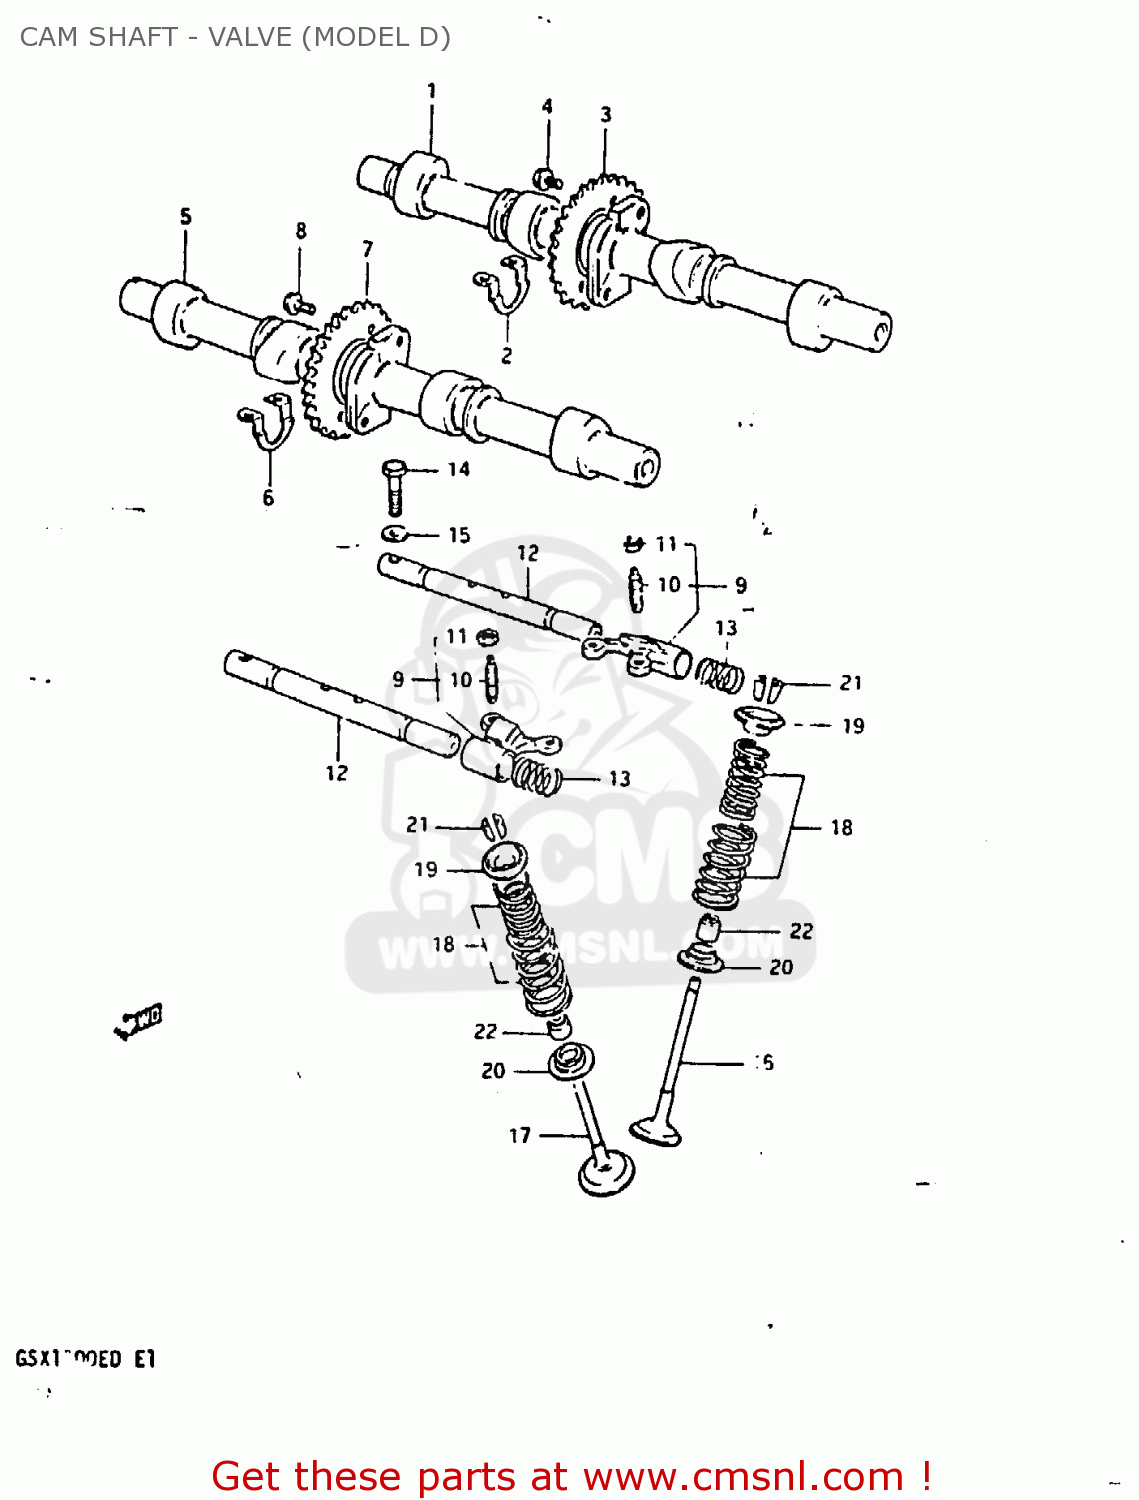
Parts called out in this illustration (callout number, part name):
1	CAMSHAFT,INTAKE
2	SHIM,CAMSHAFT
3	SPROCKET,INTAKE CAMSHAFT
4	BOLT(7X11)
5	CAMSHAFT SET,EXHAUST
6	SHIM,CAMSHAFT
7	SPROCKET,EXHAUST CAMSHAFT
8	BOLT(7X11)
9	ARM,VALVE ROCKER
10	SCREW,TAPPET ADJUSTING
11	NUT,ADJUSTING
12	SHAFT,VALVE ROCKER
13	SPRING
14	BOLT
15	WASHER
16	VALVE,INTAKE
17	VALVE,EXHAUST
18	SPRING SET,VALVE
19	RETAINER,VALVE SPRING
20	SEAT,VALVE SPRING
21	COTTER VALVE
22	OIL SEAL
